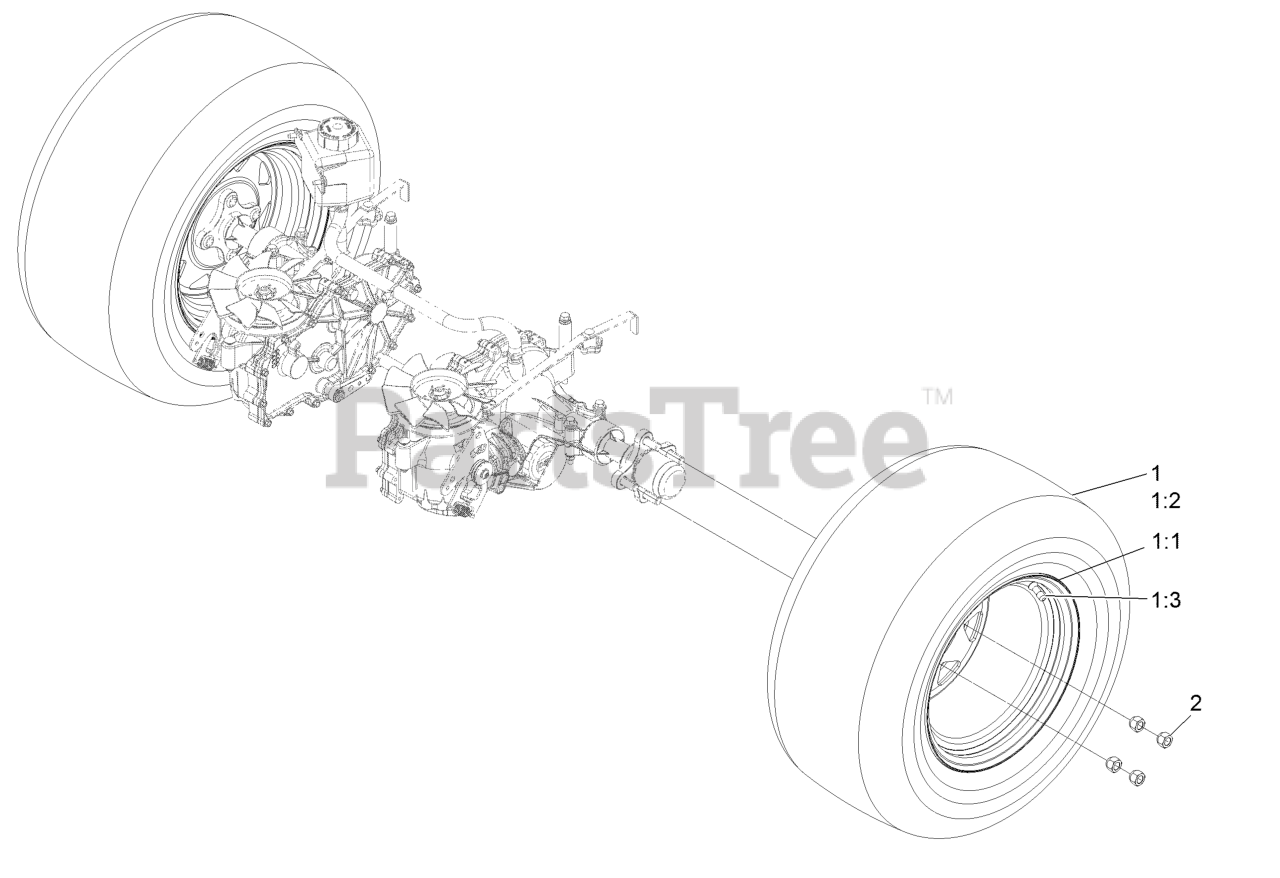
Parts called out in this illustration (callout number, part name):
1	Wheel And Tire ASM
1:1	Wheel Rim 12X8.5
1:2	Tire
1:3	Stem-Valve
2	Nut-Lug 1/2-20
